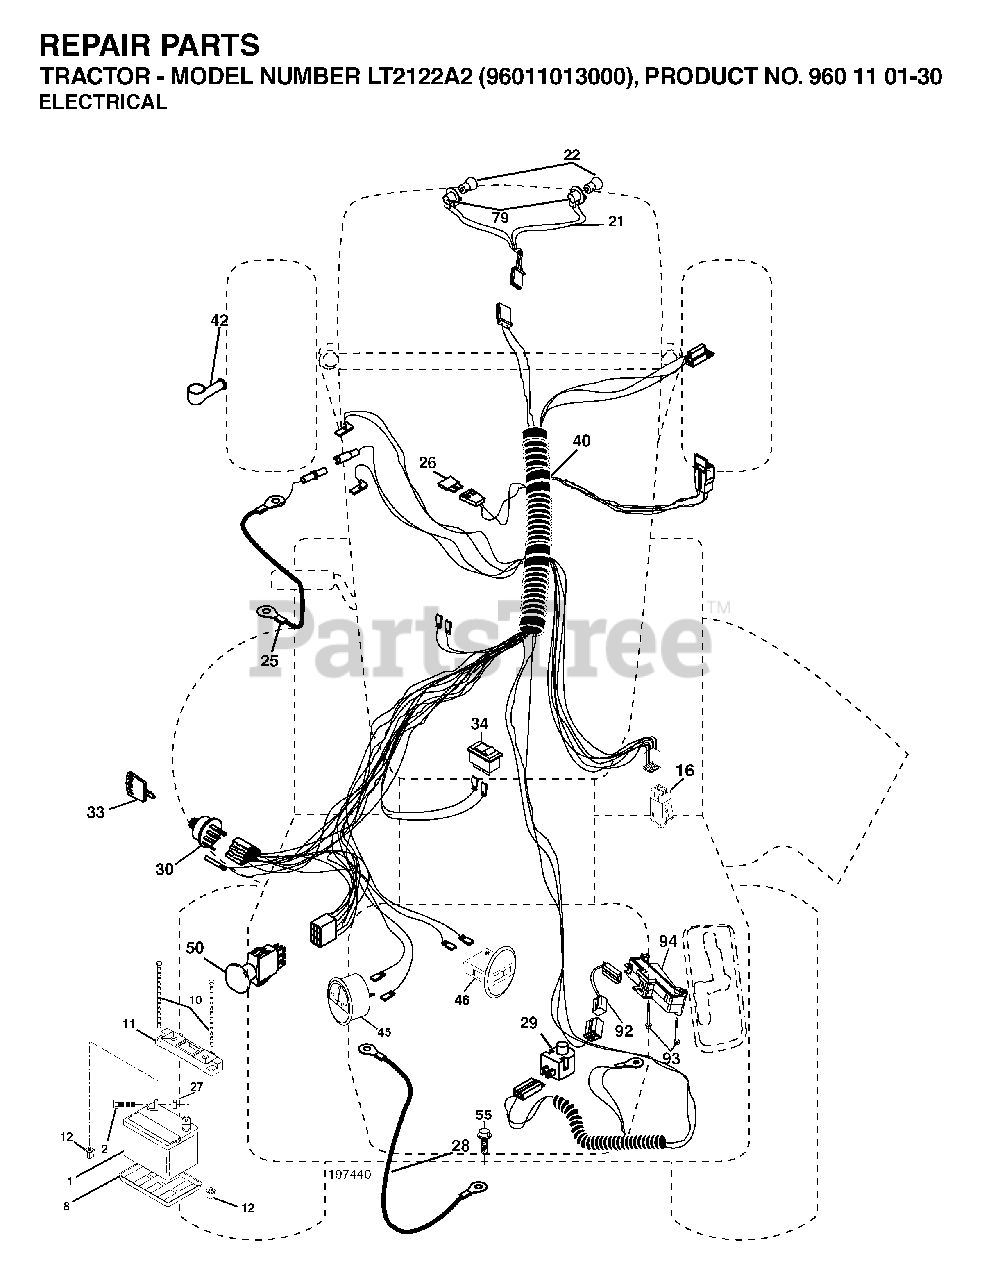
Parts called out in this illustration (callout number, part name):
1	BATTERY 12V .35 AMP
8	BATTERY TRAY T
10	BOLT 1/4-20 X 7.5
11	BATTERY HOLDDOWN
12	NUT, PUSH NYLON 1/4" BATTERY
16	SWITCH INTERLOOK PUSH-IN
21	HARNESS.W/LIGHT SOCKET
22	LIGHTBULB
26	FUSE 20AMP
27	NUT
28	CABLE GROUND 6 GA 21" 90T BLK
29	SWITCH.SEAT.DP W/RAMPS
30	SWITCH.IGN.DELTA.W.LGH.ROS
33	KEY MLD GEN DELTA
34	SWITCH LT
42	COVER.TERMINAL.RED
46	HOURMETER SNAP-IN
50	PTO SWITCH
79	BULB HOLDER ASM.
